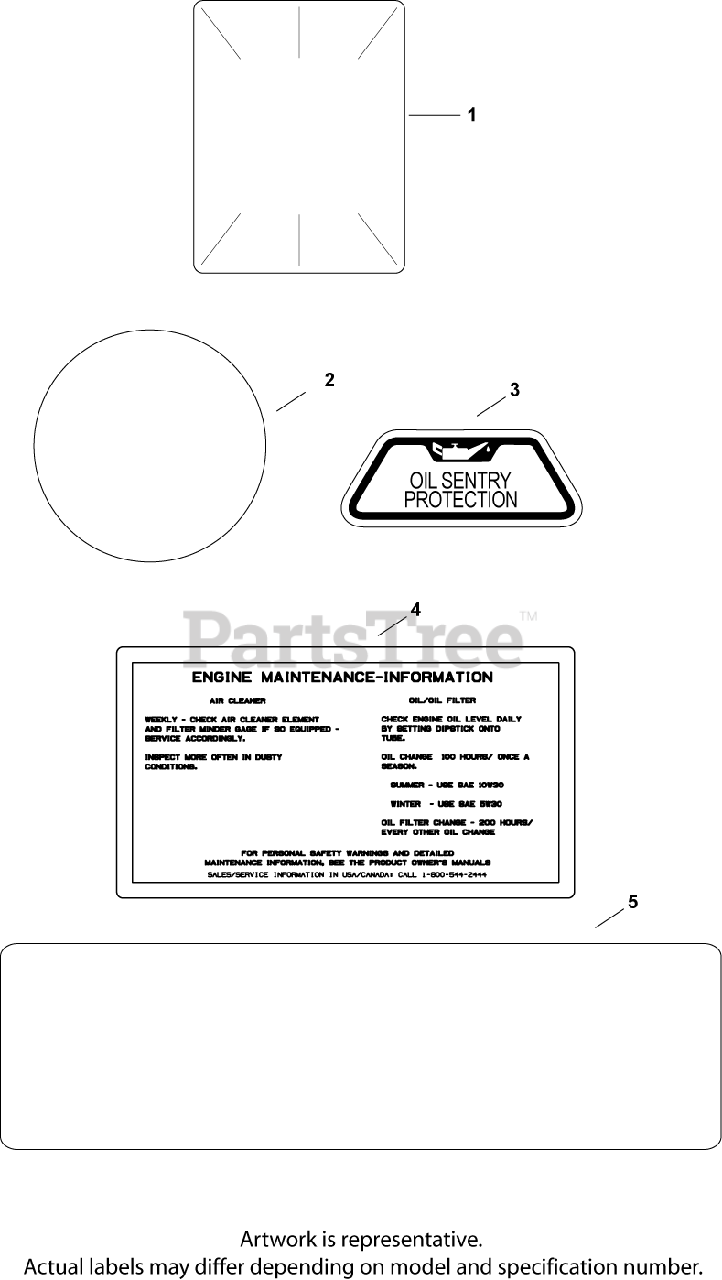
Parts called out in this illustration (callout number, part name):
1	DECAL, CLEAR LAMINATE USE 25 113 70-S
2	LABEL, (ROUND KOHLER GOLD)-USE 24 113 18
3	DECAL, OIL SENTRY - (#DSC)
4	DECAL, AIR CLEANER - (#DSC)
5	DECAL, 25 HP
